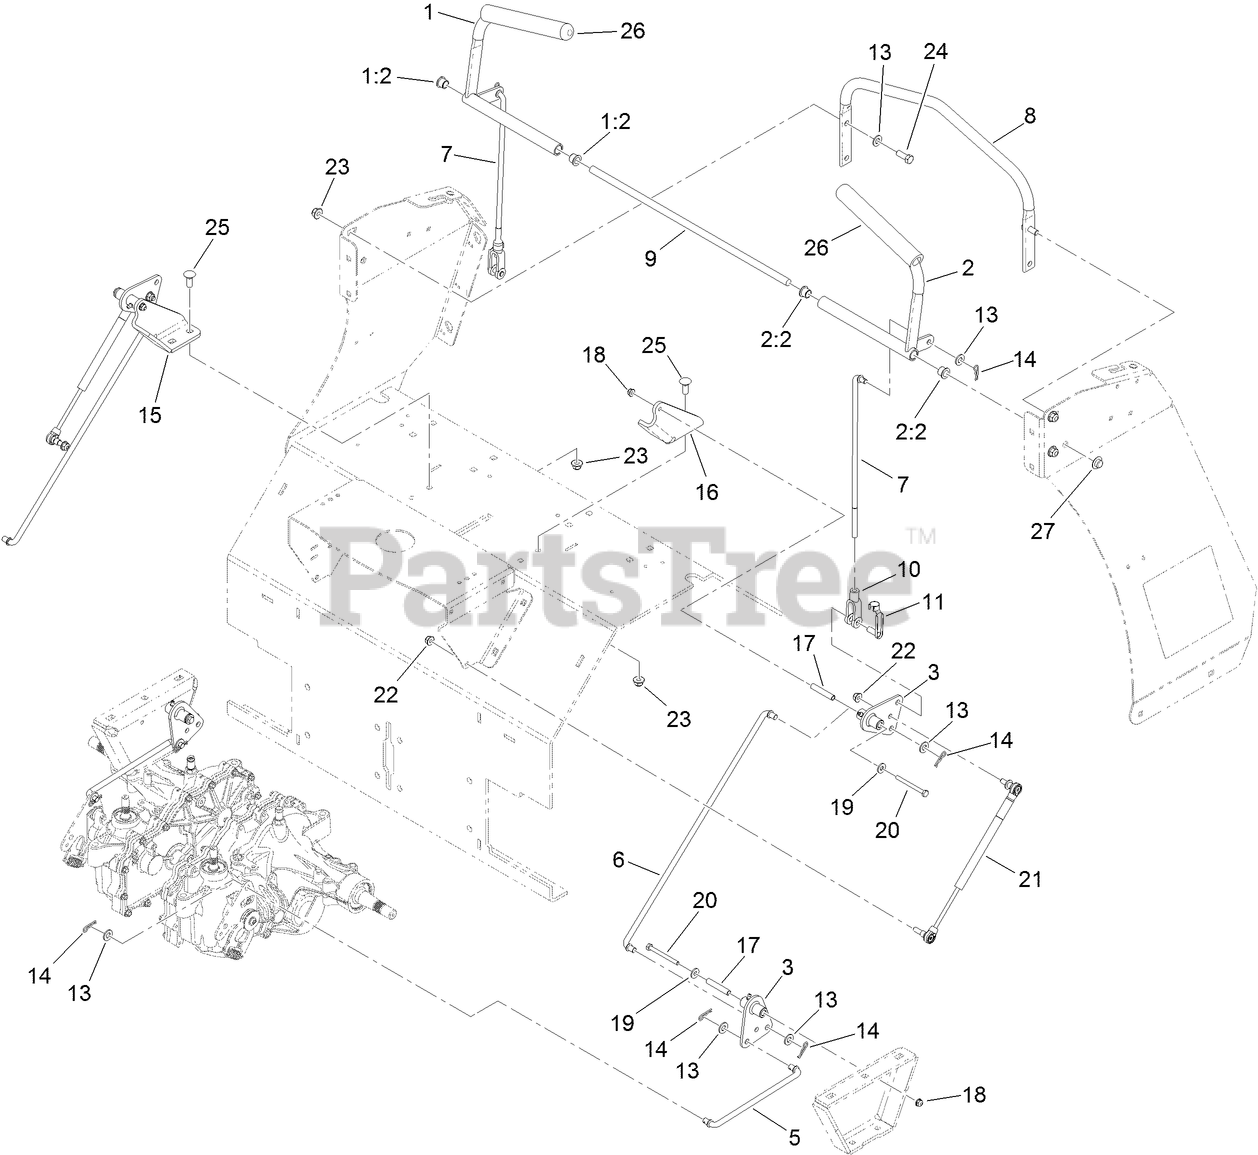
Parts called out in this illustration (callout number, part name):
1	RH CONTROL HANDLE ASM
1:2	BEARING-FLANGE
2	LH CONTROL HANDLE ASM
2:2	BEARING-FLANGE
3	CRANK-BELL
5	LINK-CONTROL, HYDRO
6	LINK-CONTROL, BELL CRANK
7	LINK-CONTROL, BELL CRANK
8	BAR-REFERENCE
9	SHAFT-PIVOT, CONTROL
10	YOKE-LINKAGE, BRAKE
11	Pin-Clevis Spring 3/8
13	Washer-3/8 SAE
14	Hairpin-Cotter
15	BRACKET-PIVOT, RH
16	BRACKET-PIVOT, LH
17	SPACER
18	Nut-Nyloc 1/4-20 Flg
19	Washer-1/4 Std
20	Screw-HH 1/4-20 x 2 3/4
21	DAMPER-CONTROL, MOTION
22	Nut-Nyloc 5/16-18 Flg
23	Nut-Nyloc 3/8-16 Flg
24	Screw-HH 3/8-16 x 1
25	Bolt-Carriage 3/8-16 x 1
26	GRIP-LEVER, CONTROL
27	NUT-PUSH
